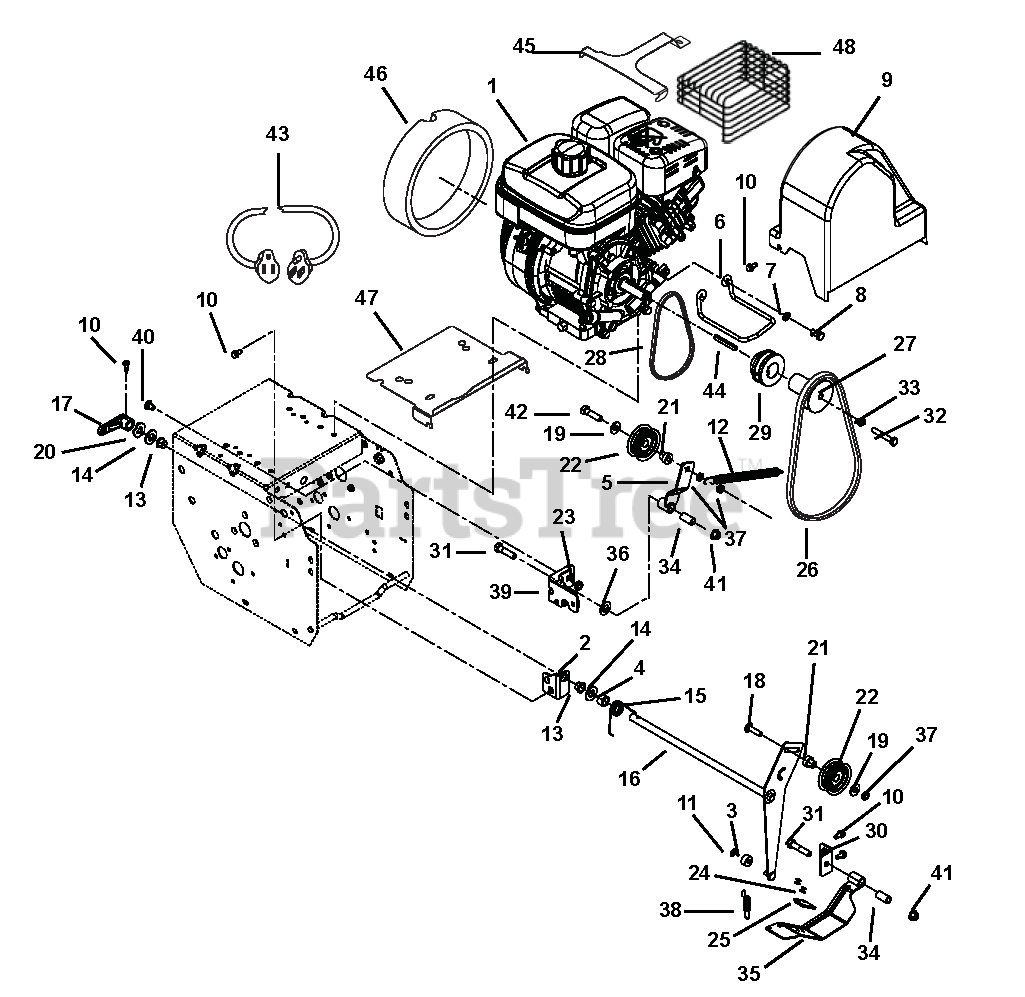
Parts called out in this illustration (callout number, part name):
1	SUBARU EX17 120V ALL-SEASON
2	BRACKET, MOUNT - IDLER ARM
3	BSHG,SLV .270 X .750 X .250
4	BSHG-SLV .510X.751X.475
5	WELDMENT, TRACTION IDLER ARM
6	BELT FINGER
7	WSHR-LK .312X.097 HVY YWZC
8	BLT-HEX .31-24X.75 YWZC GR5
9	BELT COVER
10	SCR-TAP .25-20X.50 HWH TR YWZ
11	RG-RTNG-EXT .250X.010
12	SG-TENS .062X.56X8.0 WLD 11
13	BUSHING, POLYLINER-.50 SPLIT
14	@WSHR-FL-STL.531X1.06X.095YWZC
15	SG-TORS .075 X .955
16	WELDMENT, ATTACHMENT IDLER ARM
17	ARM, CLUTCH - ATTACHMENT
18	@BLT-RHDSHSQNK.31-18X1.25 G5YZ
19	@WSHR-FL-STL.38X.875X.083 YWZC
20	WSHR-WAVE .50X.75X.015 .13FRHT
21	SPCR, BRG .315X.50X.688X.281
22	IDLER
23	@NUT-LK-TOP-FLG .31-18 YWZC
24	RVT-POP .187 YZ
25	PAD, BRAKE
26	V-BELT, HA-RAW EDGE
27	SHEAVE, ATTACHMENT DRIVE
28	V-BELT, 3L-WRAPPED
29	PULLEY, TRACTION
30	BRACKET, MOUNT - BRAKE
31	@BLT-HEX .38-16X1.75 GR5 YWZC
32	@BLT-HEX .31-24X1.75 GR5 YWZC
33	WSHR-LK .312X.097 HVY YWZC
34	BSHG-SLV .385X.500X1.045
35	BRAKE ARM W/PAD
36	@WSHR-FL-STL.406X.812X.065 YWZ
37	@NUT-LK-CTR-JAM .31-18 YWZC
38	SPRING-EXT .437 X .438 X 2.64
39	WELDMENT, FRAME BRACKET
40	@BLT-RHDSSQNK .31-18X.62 G5YZ
41	@NUT-LK-TOP-FLG .38-16 YWZC
42	@BLT-HEX .31-18X1.50 GR5 YWZC
43	CORD, ELECTRIC START CORD 120V
44	KEY-SQ .188X.75X.188
45	GUARD, SNOW-SUBARU EX17
46	FOAM COVER, RECOIL-SUBARU
47	BAFFLE,ENGINE,SMALL BLOCK
48	GUARD,MUFFLER,SUB 20A-37303-11
